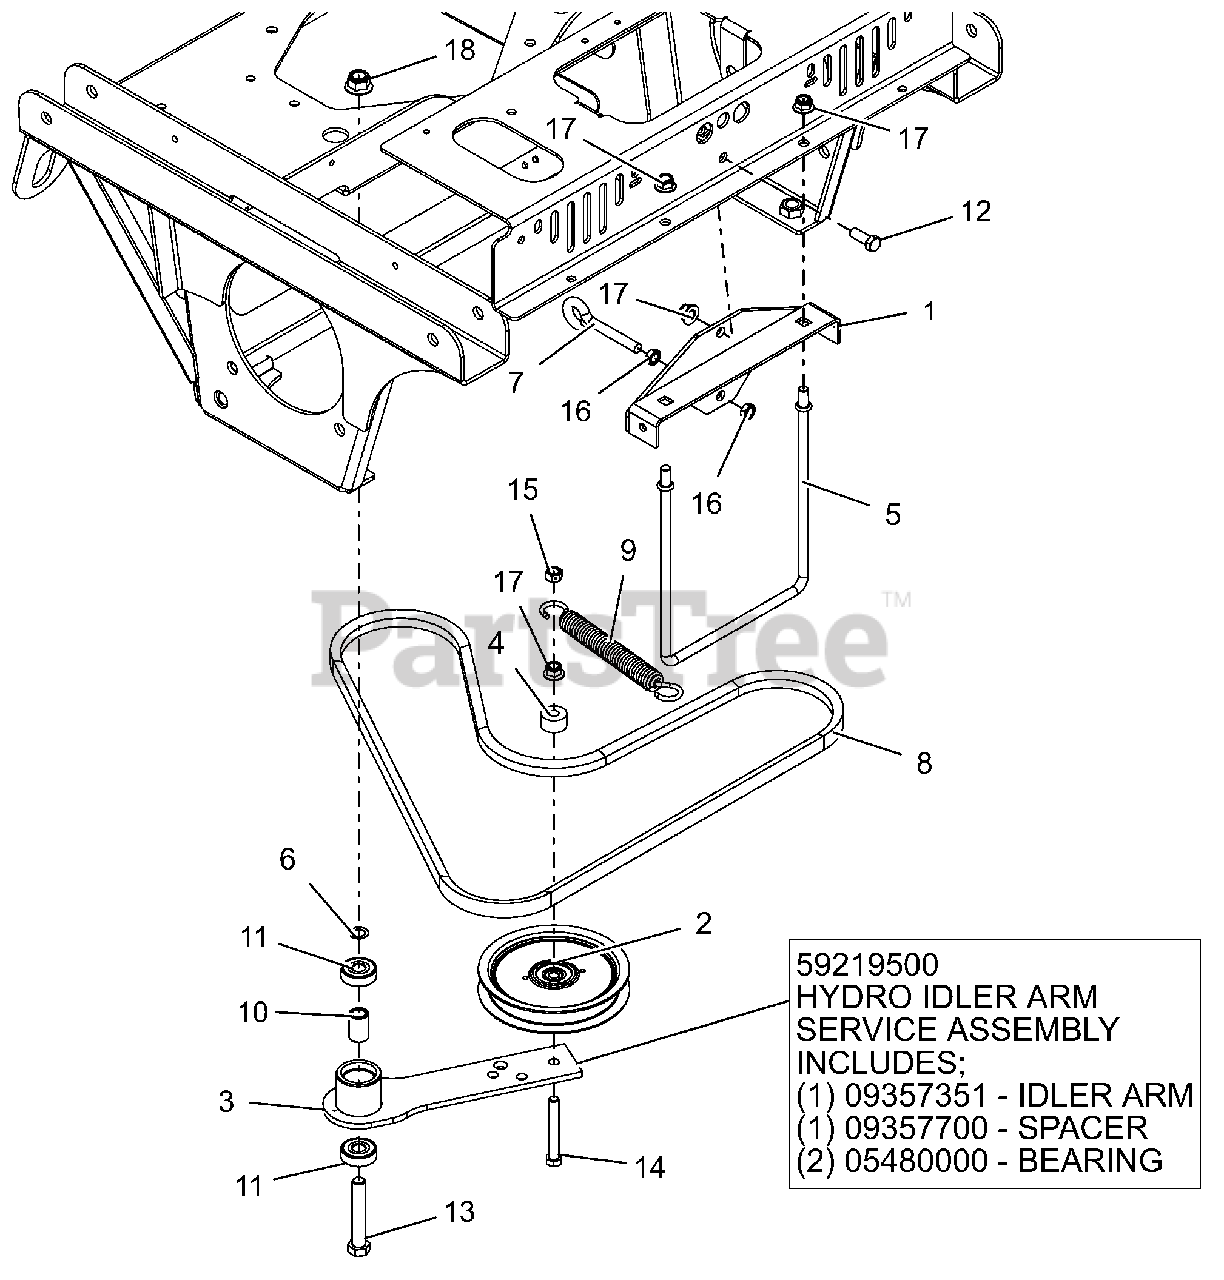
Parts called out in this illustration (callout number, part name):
1	SPRING ANCHOR BRKT WMT - BLACK
2	IDLER, FLAT-5.00X.75
3	HYDRO DRIVE IDLER ARM WMT- BLK
3	KIT, HYDRO IDLER ARM PT200/400
4	SPACER .390X1.000X.562
5	ROD, BRAKE MTG
6	WASHER, .500X.750X.020 THRUST
7	BLT-EYE .375-16X2.50 YWZC
8	V-BELT, COGGED B-RAW EDGE
9	SPRING, EXTENSION
10	SPACER .510 X .75 X 1.1485
11	BRG-BALL .500X1.38X.437
12	@BLT-HEX .38-16X1.00 GR5 YWZC
13	@BLT-HEX .50-13X3.00 GR5 YWZC
14	@BLT-HEX .38-16X2.75 GR5 YWZC
15	@NUT-LK-CTR .38-16 YWZC
16	NUT-HEX-JAM .375-16 YWZC
17	@NUT-LK-NYL-FLG .38-16 YWZC
18	@NUT-LK-NYL-FLG .50-13 YWZC
